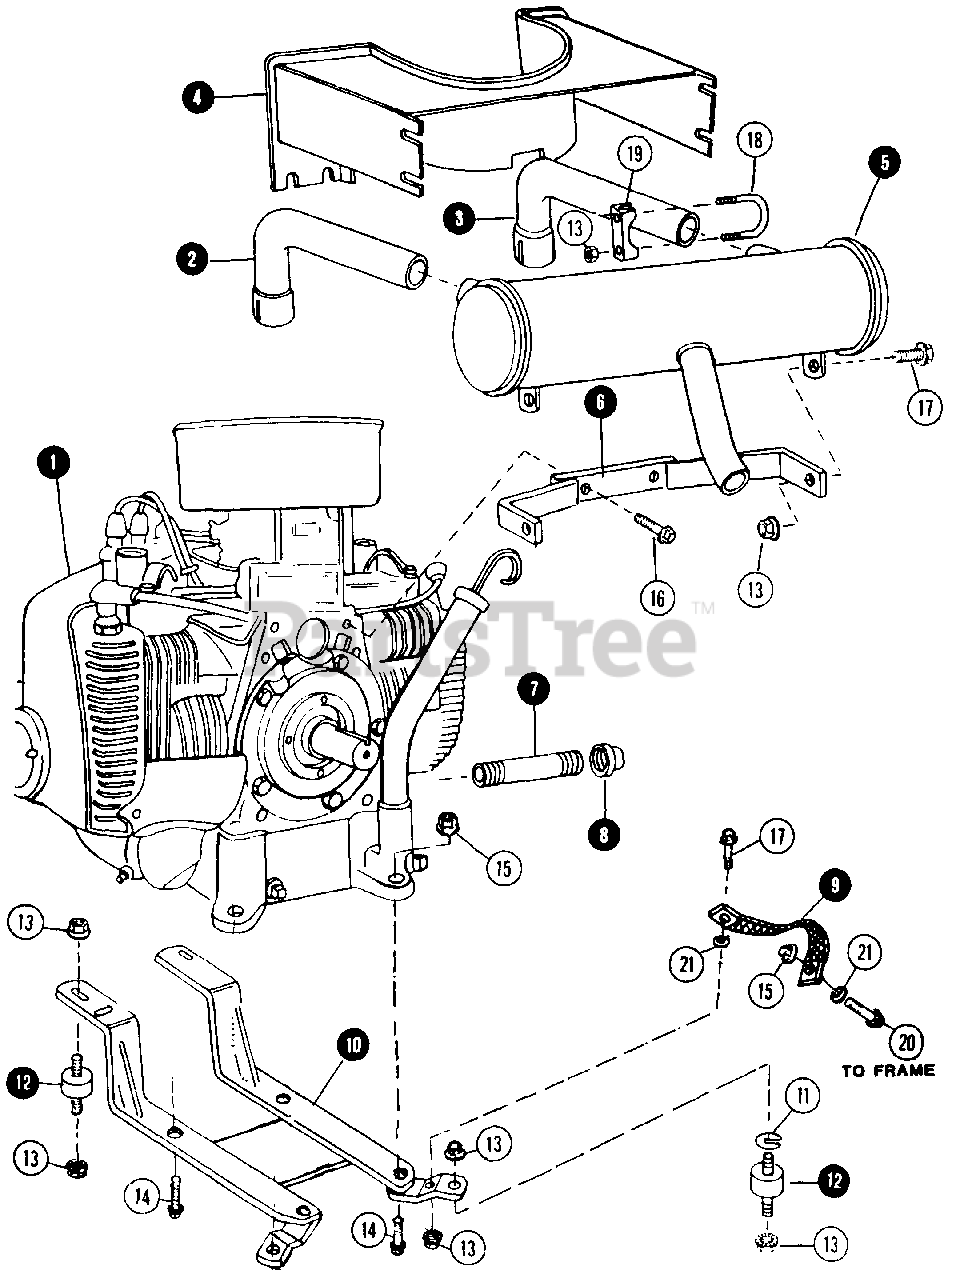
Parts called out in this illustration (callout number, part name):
2	PIPE, RIGHT SIDE EXHAUST
3	PIPE, LEFT SIDE EXHAUST
4	SHIELD HEAT
5	MUFFLER, STANDARD EXHAUST
6	BRACKET, MUFFLER MOUNTING
7	NIPPLE, OIL DRAIN PIPE
8	CAP, DRAIN - 3/8 SQUARE HEAD PIPE
9	STRAP, ENGINE GROUND
10	BRACKET, ENGINE MOUNTING
11	C-WASHER
12	DAMPENER, ENGINE VIBRATION MOUNT
13	NUT, 5/16C HEX FLANGE LOCK
14	BOLT, 3/8C x 1-1/2 HEX FLANGE
15	NUT, 3/8C HEX FLANGE LOCK
16	BOLT, 3/8C x 1" HEX FLANGE
17	BOLT, 5/16C x 3/4 HEX FLANGE
18	U-BOLT EXHAUST PIPE
19	CLAMP, U-BOLT
20	BOLT, 3/8C x 1" CARRIAGE
21	WASHER, 3/8 EXTERNAL TOOTH LOCK
